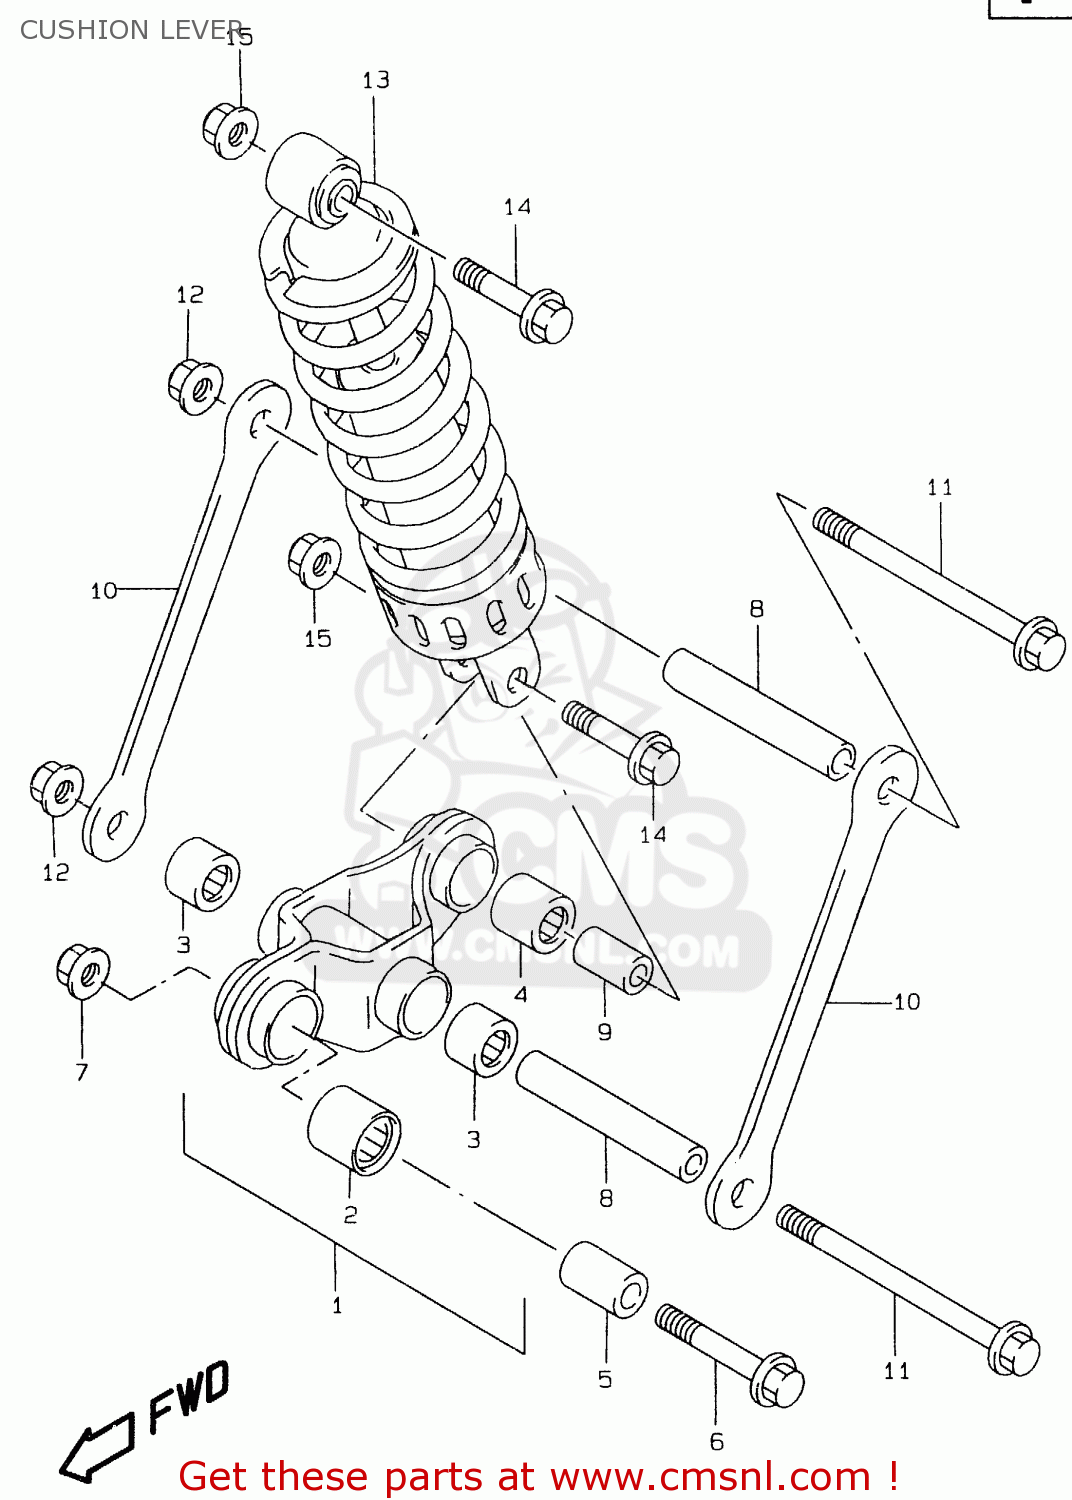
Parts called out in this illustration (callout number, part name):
1	LEVER SET,RR CUSHION
2	BEARING(20X27X26)
3	BEARING(17X24X25)
4	BEARING(17X24X26)
5	SPACER,RR CUSHION LEVER FR
6	BOLT(12X57)
7	NUT 12MM
8	SPACER (12X17X89)
9	SPACER,RR CUSHION LEVER
10	ROD,RR CUSHION LEVER
11	BOLT(12X118)
12	NUT 12MM
13	ABSORBER ASSY,RR SHOCK
14	BOLT(10X52)
15	NUT
